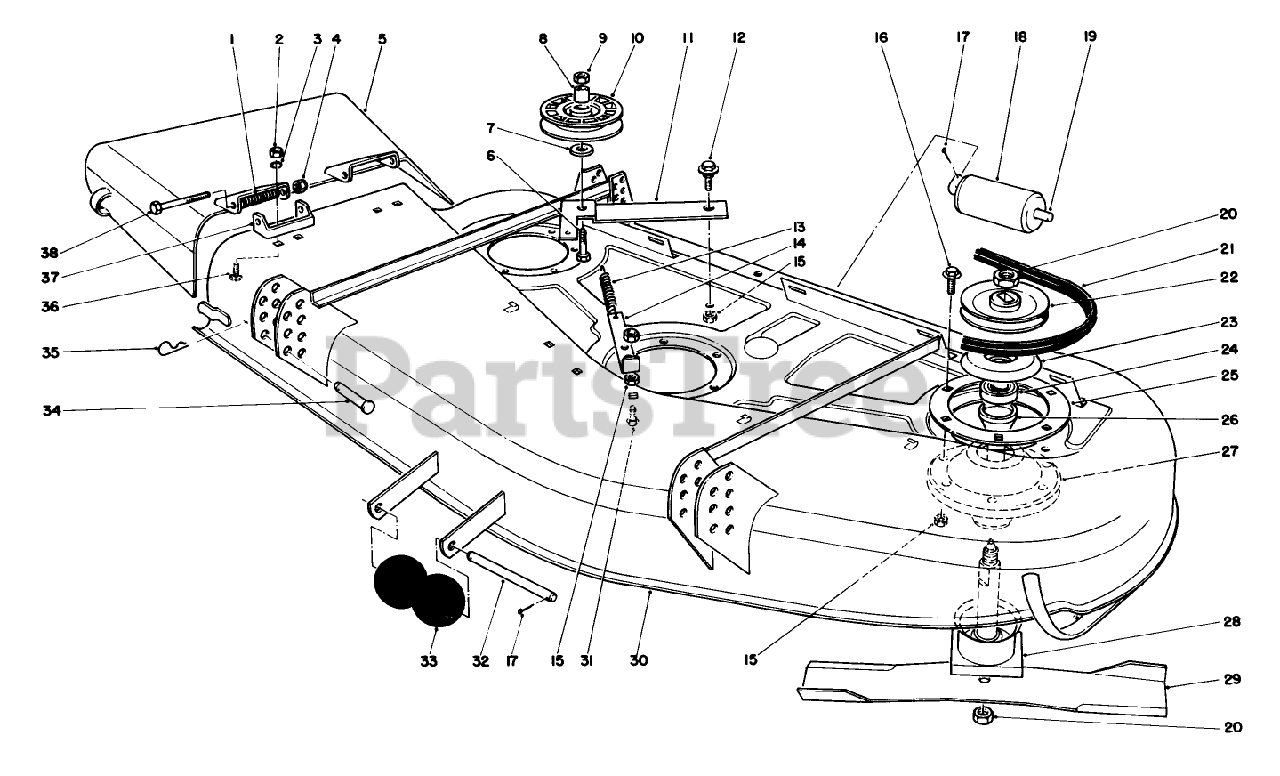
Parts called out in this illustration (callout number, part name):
1	SPRING
2	NUT-HEX
3	WASHER-LOCK
4	NUT-HEX
6	SCREW-HH
7	Washer
9	NUT-LOCK, NI
12	SCREW-SHOULDER
13	SPRING-EXTENSION, DECK
15	NUT-LOCK, NI
16	SCREW-HHF
17	PIN-COTTER
18	ROLLER-DECK
19	SHAFT-ROLLER, REAR
21	V-BELT, DECK
24	BEARING
31	SCREW-CARR
32	SHAFT-ROLLER
33	ROLLER
34	PIN-CLEVIS
35	PIN-HAIR
38	SCREW-HH
